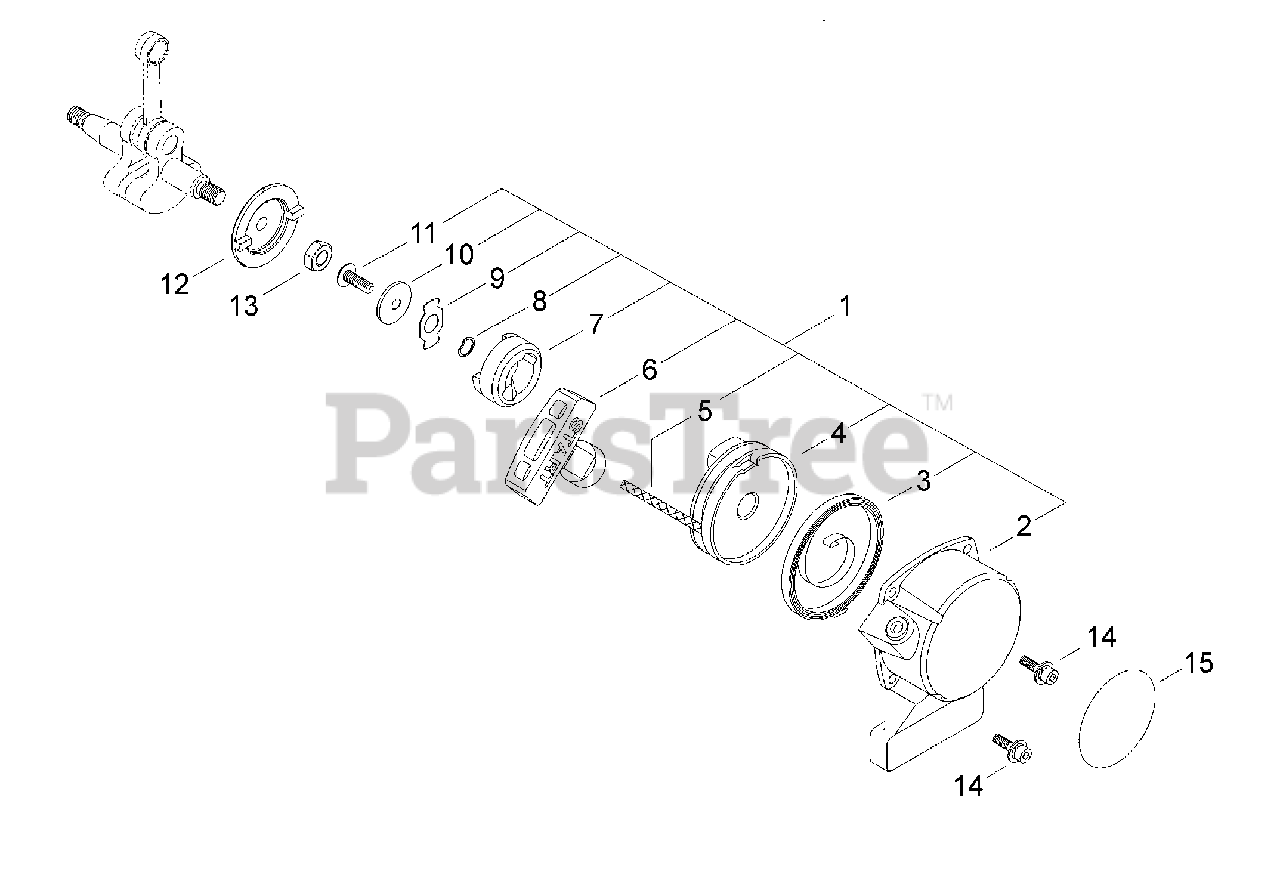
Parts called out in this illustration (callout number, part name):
1	STARTER ASSY
2	CASE, STARTER
3	SPRING, REWIND
4	REEL, ROPE
5	ROPE, STARTER
6	GRIP, STARTER
7	PAWL, STARTER
8	WASHER - SPRING
9	RETAINER
10	WASHER - 5
11	SCREW - 5
12	PAWL
13	NUT - 8
14	SCREW - 4X16
15	LABEL - C4
